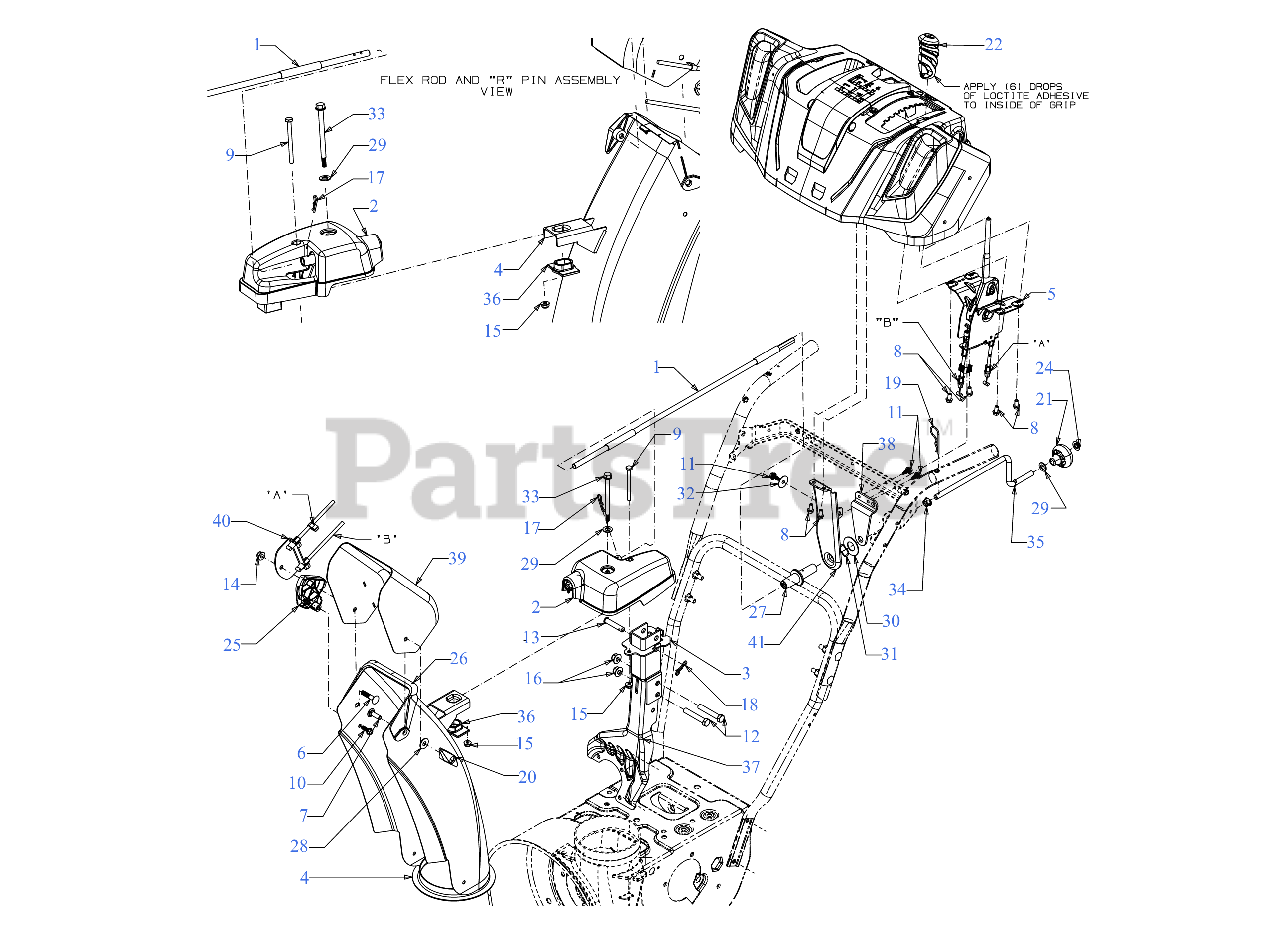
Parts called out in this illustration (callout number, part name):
1	CHUTE CONTROL SHAFT
2	GEARBOX ASSEMBLY
5	2-WAY STEEL CHUTE CONTROL ASSEMBLY
6	CARRIAGE BOLT 5/16-18 x 1.50
7	CARRIAGE BOLT 5/16-18 x 1.00
8	HEX SCREW 1/4-15 x .50
9	SCREW 1/4-20 x 3.0 GR5
10	SCREW 1/4-15 x .750
11	SCREW 1/4-20X.625
12	SCREW 3/8-16 x 2.25 GR5
13	CLEVIS PIN 3/8 x 1.87
14	FLANGE LOCK NUT 5/16-18
15	FLANGE LOCK NUT
17	INTERNAL COTTER PIN-1/2 DIA
18	BOW TIE COTTER PIN 1/4-5/16
19	INTERNAL COTTER PIN
20	WING KNOB NUT
21	SHIFT KNOB
22	PTO HANDLE GRIP .355 ID
24	PUSH NUT
25	CHUTE TILT GUIDE
26	UPPER CHUTE ADAPTER
27	CHUTE ROD COUPLER
28	FLAT WASHER
29	FLAT WASHER
30	FLAT WASHER
31	WAVE WASHER .785X1.00X.012
32	FLAT WASHER
33	SHOULDER SCREW
34	BUSHING .380 ID
35	CHUTE CRANK (POWDER BLACK)
36	HELICAL GEAR CHUTE ADAPTER
38	ROD SUPPORT BRACKET
